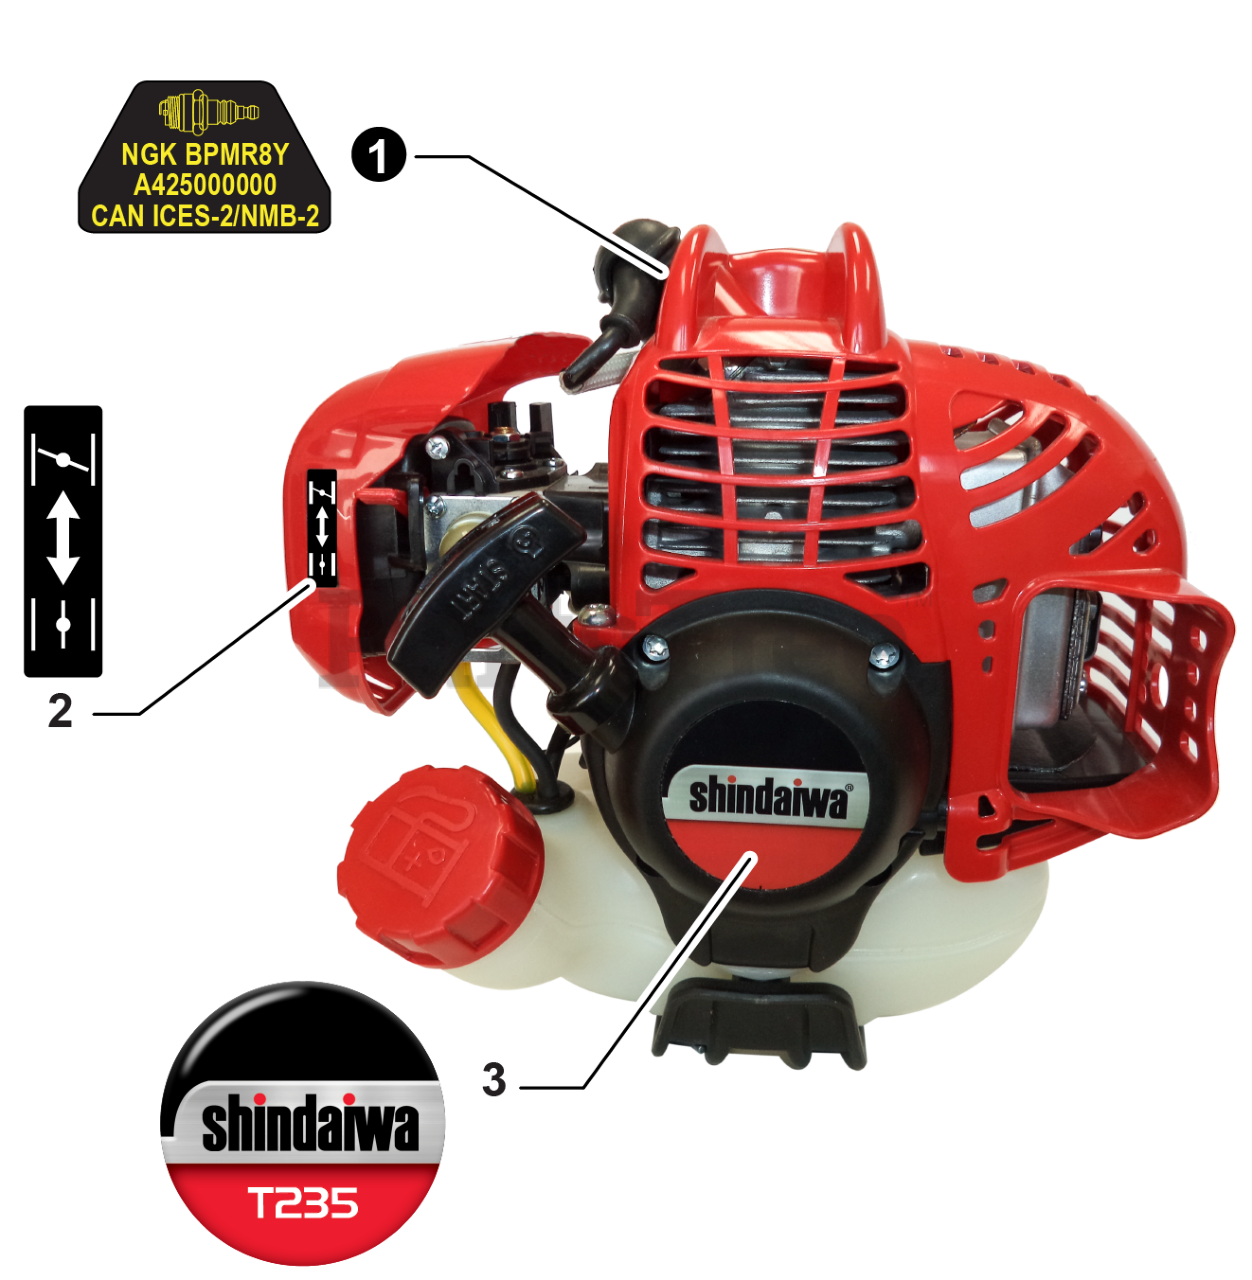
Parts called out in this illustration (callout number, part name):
1	LABEL - SPARK PLUG - BPMR8Y
2	LABEL - CHOKE
3	LABEL - SHINDAIWA - T235
